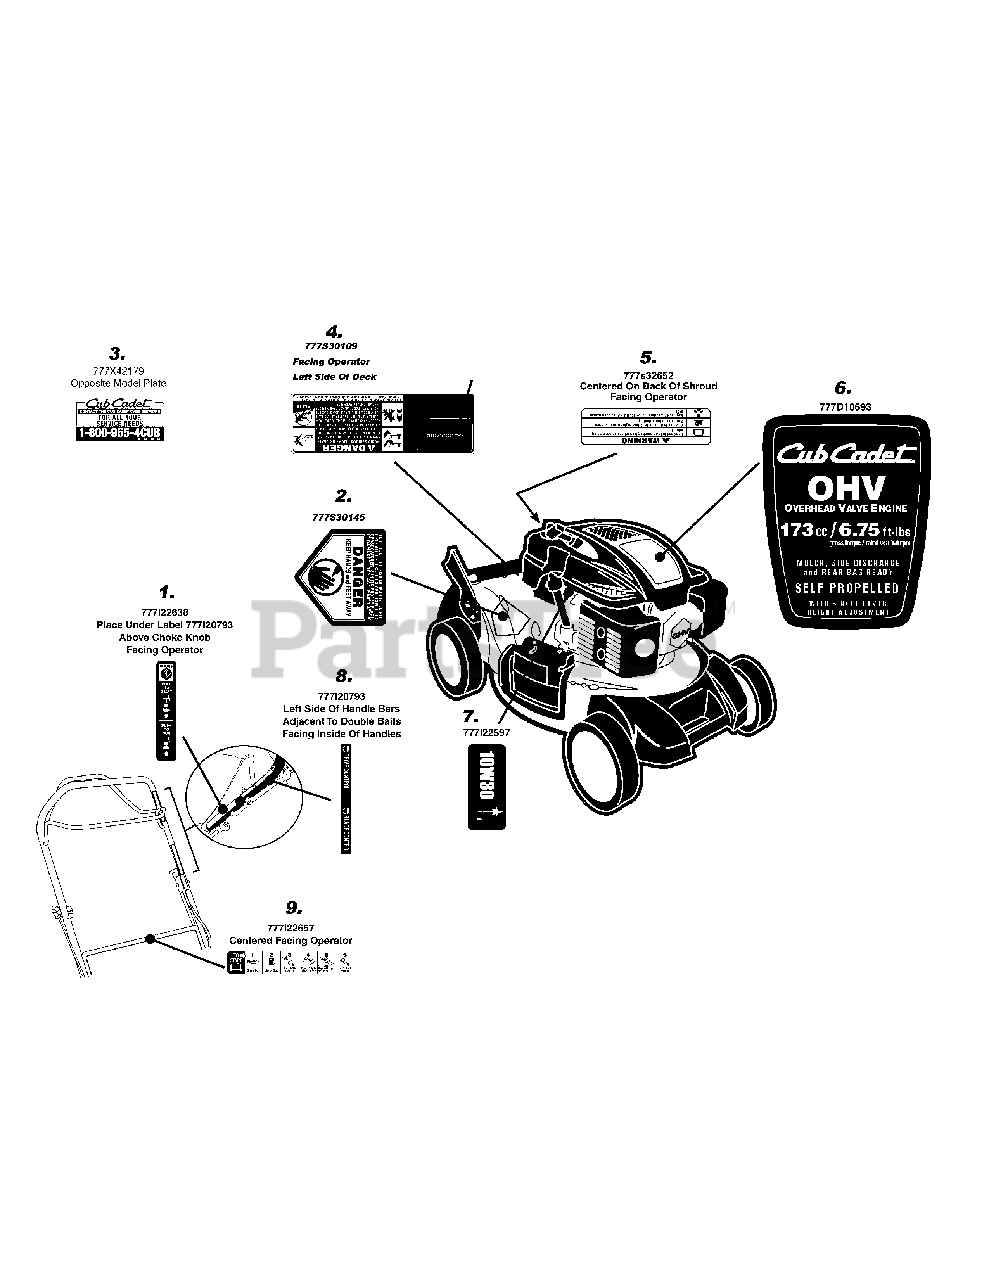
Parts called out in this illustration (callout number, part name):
1	LABEL-MOWER HANDLE:CHOKE START/RUN
2	LABEL
3	LABEL-CUB HOTLINE
4	LABEL-MOWER DANGER
5	LABEL:MOWER:ENGINE SHROUD
6	LABEL-CC550 SP ENG SHROUD
7	LABEL:MOWER SHROUD
8	LABEL-HANDLE
9	LABEL-MOWER HANDLE
